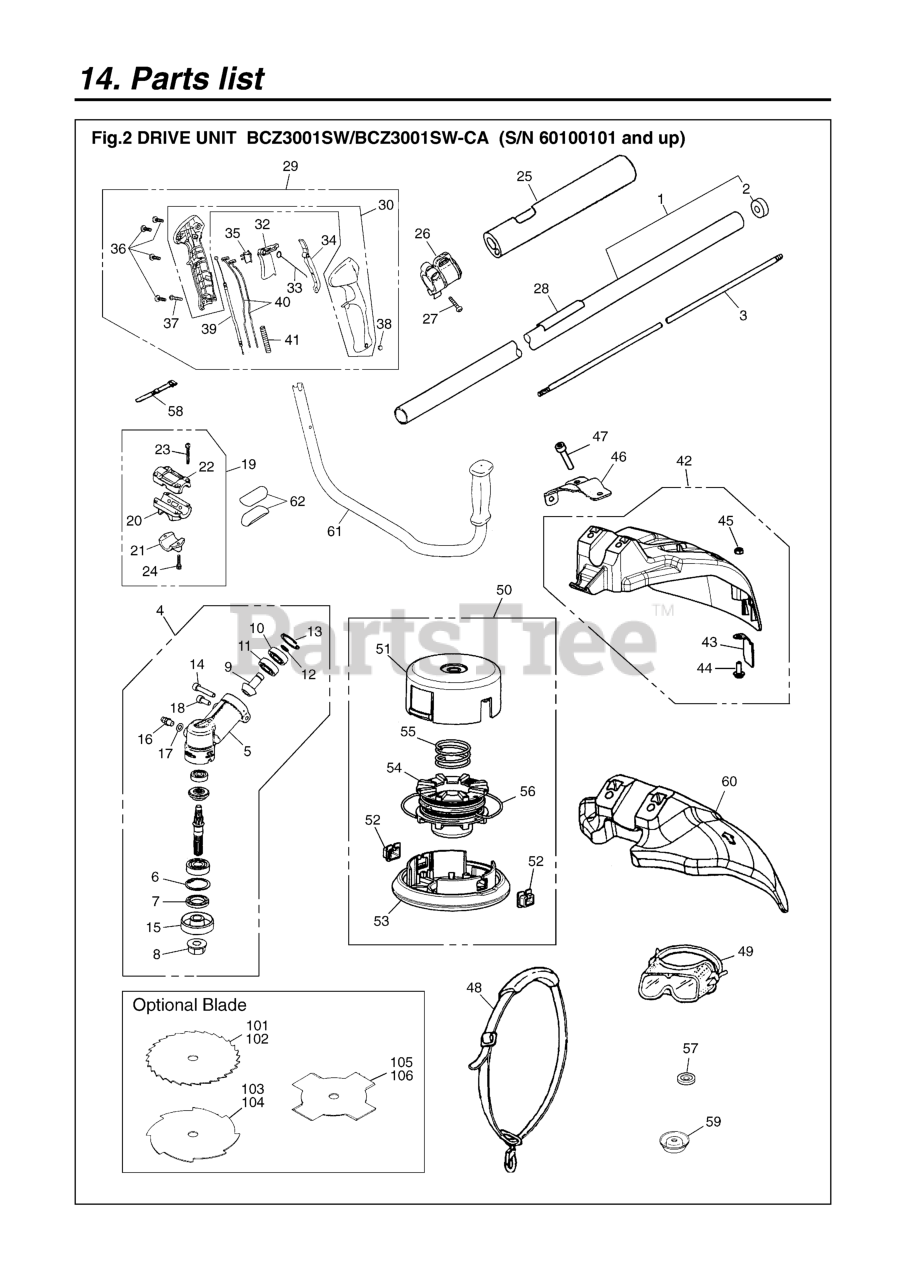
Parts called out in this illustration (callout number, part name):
1	PIPE COMP.
2	SEAL
3	SHAFT (RPLS -12212)
4	GEARCASE ASSY.
5	GEARCASE
6	RING, SNAP M26x1.2 R-318013340
7	SEAL, OIL
8	NUT
9	PINION
13	RING, SNAP, M24 x 1.2
14	BOLT, TORX
15	HOLDER (A)
16	FITTING, GREASE
17	WASHER, M6 X .8
18	BOLT, TORX
19	BRACKET ASSY
20	BRACKET
22	BRACKET-UP
23	BOLT (RPLS 2850-14220)
25	PROTECTOR
26	HANGER COMP.
27	SCREW
28	NAME PLATE
29	GRIP ASSY
30	HANDLE HALF SET
32	LEVER
33	SPRING
34	LEVER-S
35	SWITCH
36	SCREW
37	SCREW TORX
38	NUT
39	CABLE COMP
40	CORD COMP
41	TUBE
42	GUARD COMP(RPLS 848JC06610)
43	BLADE (RPLS T3002-24120)
44	SCREW TORX
45	NUT
46	BRACKET
47	BOLT, TORX
48	STRAP ASSY. (USE 848-JC0-3610)
49	GOGGLE
50	TAP HEAD COMP.
51	CASE (REPLACES -15111)
52	EYELET
53	COVER (REPLACES -15131)
54	HOLDER, CORD (REPLACES-15141)
55	SPRING
56	CORD
57	HOLDER (B)
58	BAND
59	COVER (10mm)
60	GUARD
61	HANDLE COMP
62	PLATE
101	BLADE, 9
102	BLADE, 9
103	BLADE, 8
104	BLADE, 9
105	BLADE, 8
106	BLADE, 9
